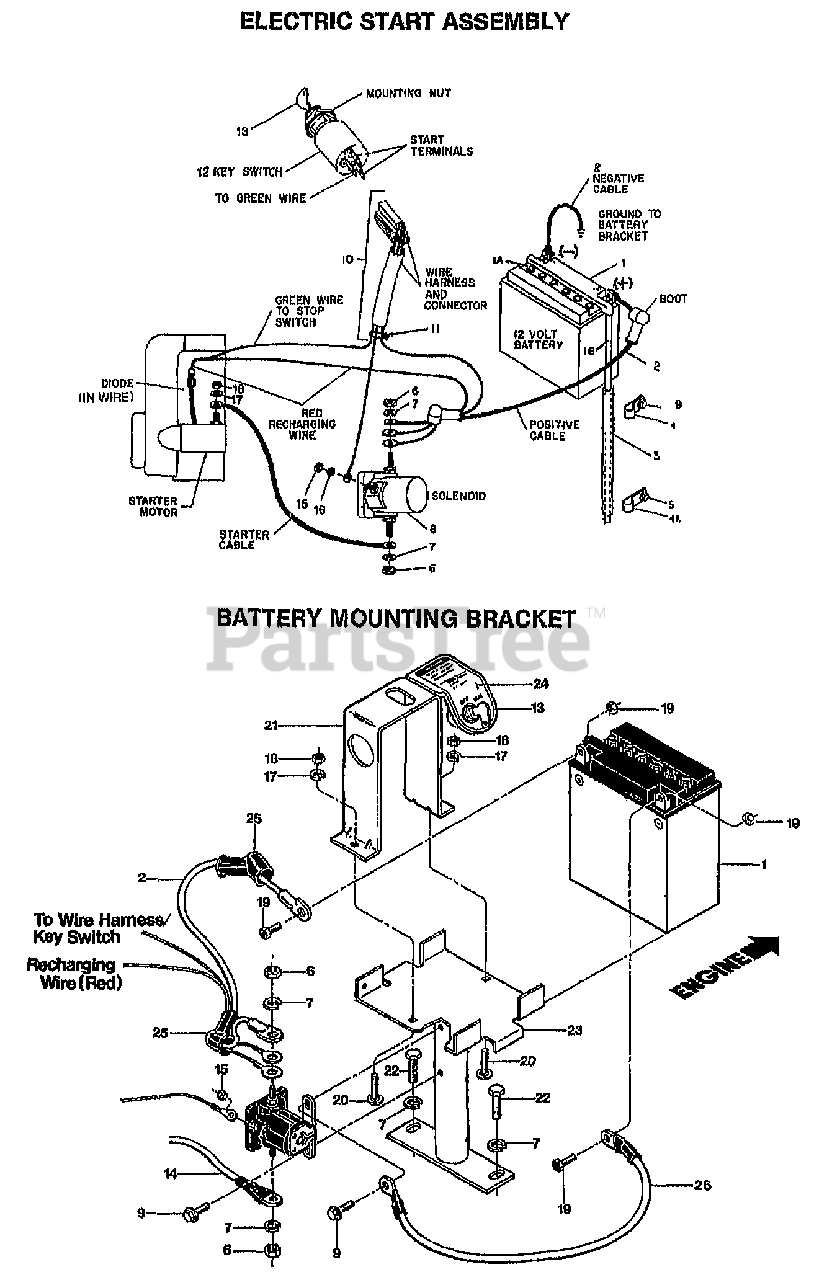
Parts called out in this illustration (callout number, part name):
1	BATTERY 12 VLT, 12 AMP
1A	CAP-YELLOW
1A	CAP-BATTERY WHITE (PONY)
1B	TUBE-VENT BATTERY/HSE
2	CABLE-BATTERY POS.
3	TUBING-RUBBER
4	CLAMP
4A	CLAMP-VENT TUBE 9/16 OPC
5	SCR-HH 1/4-20X.625
6	NUT-HEX 5/16-24
7	WASHER-LK .312 ZP
8	KIT-SOL W/HDW (INCL NUTS & WSHRS FOR CBLE WRE)
9	SCR-HWH 1/4-20 X .5 STH
10	HARNESS-WIRE 3.5
11	TIE-TWIST LOCK
12	KEYSWITCH W/2 KEYS
13	KEYS(1 PAIR) FOR SWITCH
14	CABLE-BATTERY (SOLENOID TO SRTR)
15	NUT W/LKWASHER #10-32 ZP
16	WASHER-EXTERNAL TOOTH 1
17	WASHER-LK .25 ZP
18	NUT-HEX 1/4-20 ZP
19	HDW PKG-BATT TERM (ATTACH BATT CBLS TO POSTS)
20	SCR-CARR 1/4-20X1.25
21	PLATE-KEYSWITCH (INCL DECAL #20820)
22	SCR-HH 5/16-18X1.0 G5 ZP
23	BRKT-BATTERY OPC PNT
24	DECAL-KEYSWITCH
26	CABLE-BATTERY 13.5"
